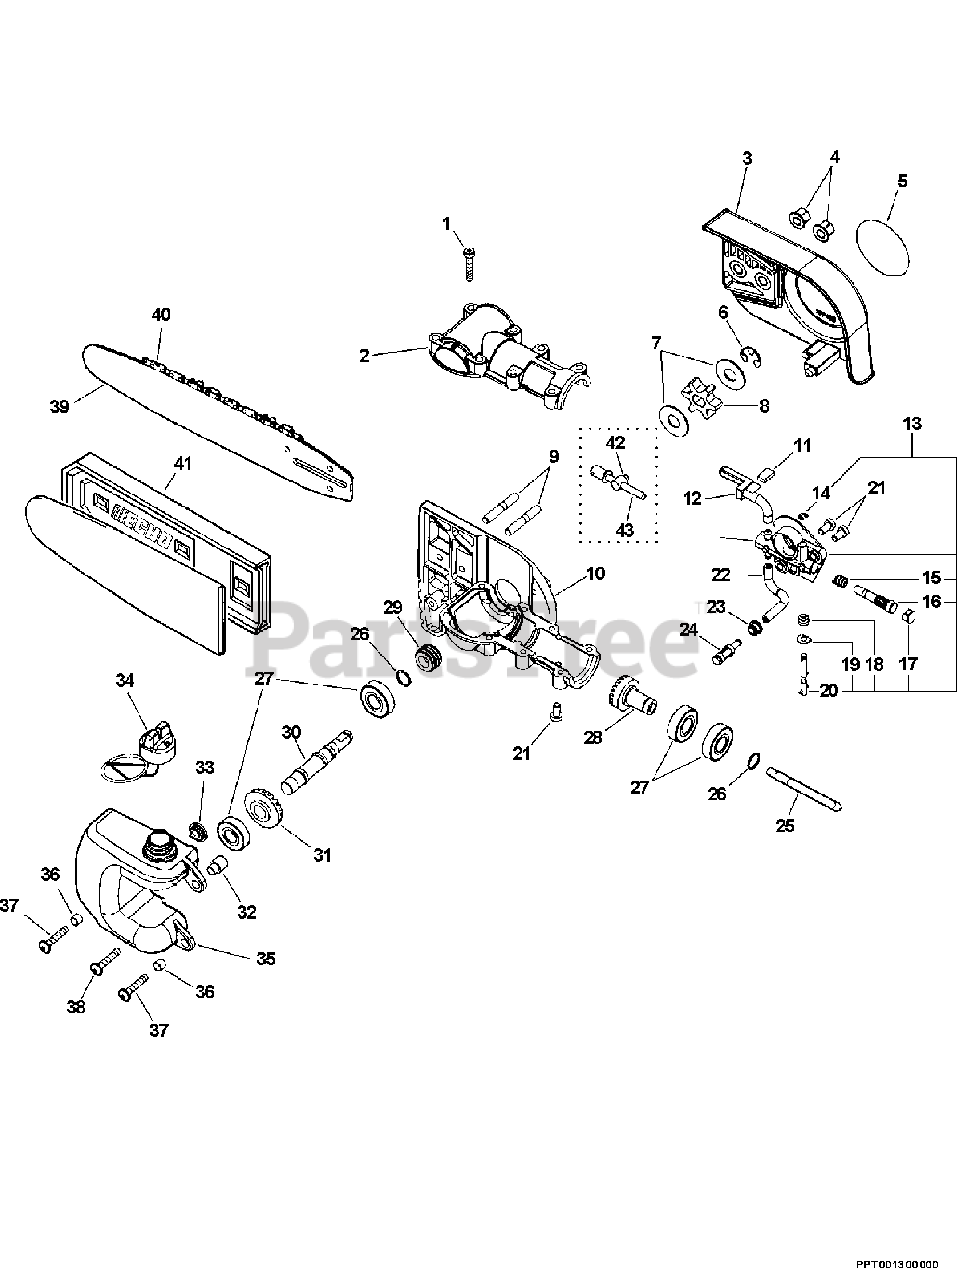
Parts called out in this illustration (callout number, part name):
1	SCREW - 5X25
2	CASE, GEAR - UPPER
3	GUARD, SPROCKET
4	NUT - 6 -- FLANGE
5	LABEL - ECHO
6	RING, RETAINING
8	SPROCKET, DRIVE
9	STUD - 6
10	CASE, GEAR - LOWER
11	PAD, FOAM
12	PIPE, OIL OUTLET
13	AUTO-OILER ASSY
14	RING, RETAINING
15	SPRING, PLUNGER
16	PLUNGER ASSY
17	CAP, OIL PUMP
20	NEEDLE, ADJUST
21	SCREW - 5X10
22	PIPE - 3X6X75 -- BLACK
23	GROMMET
24	FILTER, OIL
25	CONNECTOR, SHAFT
26	RING, RETAINING - 12
27	BEARING, BALL - 6001
28	GEAR - BEVEL
29	GEAR - WORM
30	GEAR - SHAFT
31	GEAR - BEVEL
34	CAP ASSY
35	TANK, OIL
37	SCREW - 5X16
38	SCREW - 5X20
39	GUIDE BAR - 12" (30cm) Intenz
40	SAW CHAIN - 12" (30cm)
41	COVER, GUIDE BAR - 12" (30cm)
42	TENSIONER, CHAIN
43	SCREW, TENSIONER
